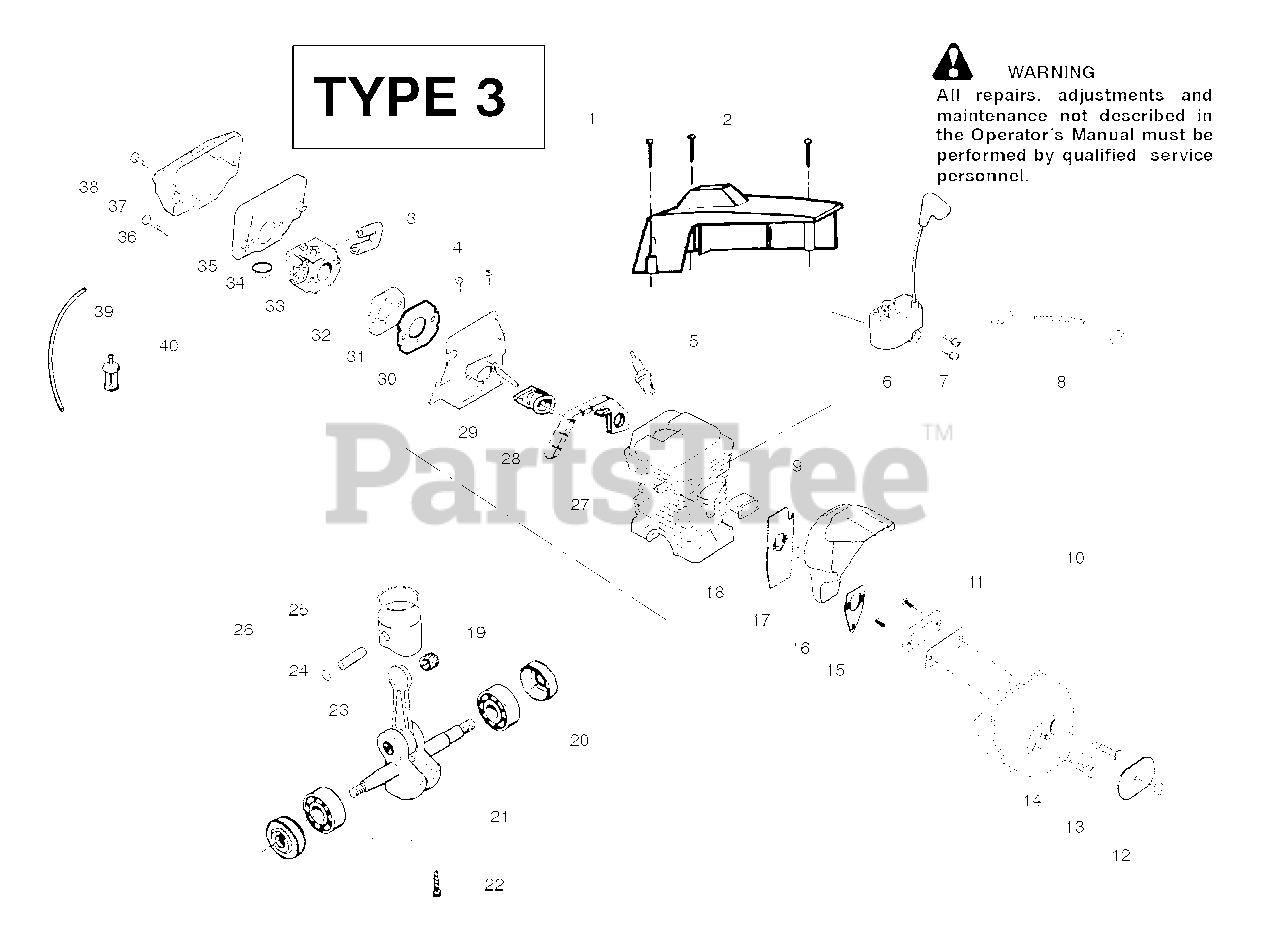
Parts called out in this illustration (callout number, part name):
2	Kit-Cylinder Shield
3	Grommet -Carb.
5	Spark Plug
6	Module-Ignition
8	Assy-Switch Wire
9	Insulator-Heat
10	Kit-Muffler
11	Kit-Spark Arrestor
12	Nut-Brass
13	Cover-Bolt
14	Bolt-Muffler
15	Screw-Spark Screen
16	Gasket-Muffler
17	Assy-Muffler Backplate
18	Backplate - Alum.
20	Assy-Bearing & Seal
21	Cap-Crankcase
23	Assy-C'shaft & Rod
24	Retainer-Piston Pin
25	Ring-Piston
26	Kit-Piston
27	Assy-Cyl/Crankcase
28	Seal-Super Clean
29	Intake Boot
30	Adapter-Carb.
31	Intake Plate-Carb
32	Gasket-Carb.
33	Kit-Carburetor
34	Isolator
35	Filter-Air
37	Filter-Air
39	Kit-Fuel Line
40	Assy-Fuel Pick-up
